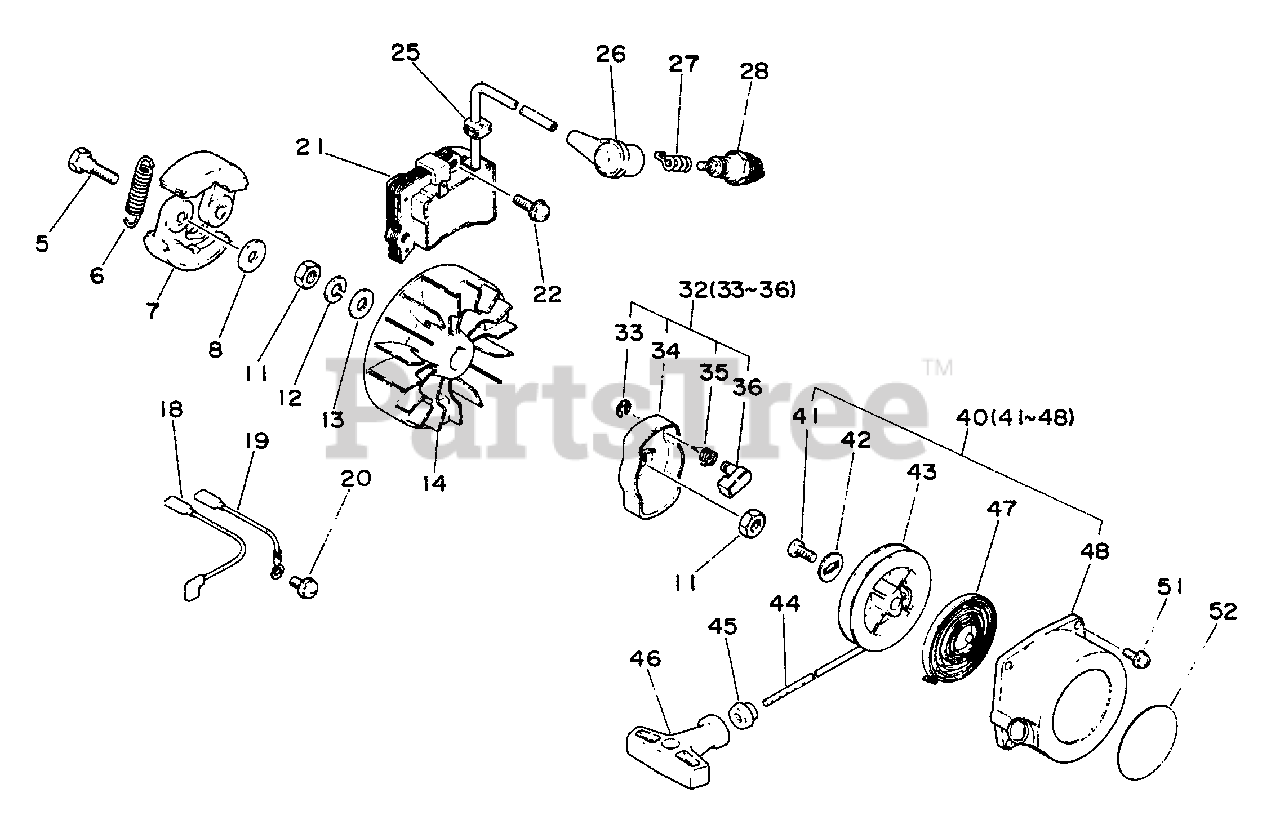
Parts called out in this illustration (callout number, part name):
5	BOLT, CLUTCH
6	SPRING, CLUTCH
7	SHOE, CLUTCH
8	WASHER 6.2×19×1.0
11	NUT 8×1.25
12	WASHER, SPRING 8
13	WASHER 8.5×16×1.2
14	FLYWHEEL
18	LEAD
19	LEAD - GROUND
20	SCREW 5×10
21	COIL, IGNITION
22	SCREW 5×20
26	CAP, SPARK PLUG
27	TERMINAL, SPARK PLUG
28	SPARK PLUG - CJ-7Y
32	PAWL ASSY, STARTER
33	RING, RETAINING - 6
34	CATCHER, PAWL
35	SPRING, RETURN
36	PAWL, STARTER
40	STARTER ASSY
42	WASHER
43	REEL, ROPE
44	ROPE, STARTER 3.5×850
45	GUIDE, ROPE
46	GRIP, STARTER
47	SPRING, RECOIL
48	CASE, RECOIL STARTER
51	SCREW 4×14
52	LABEL, ECHO
